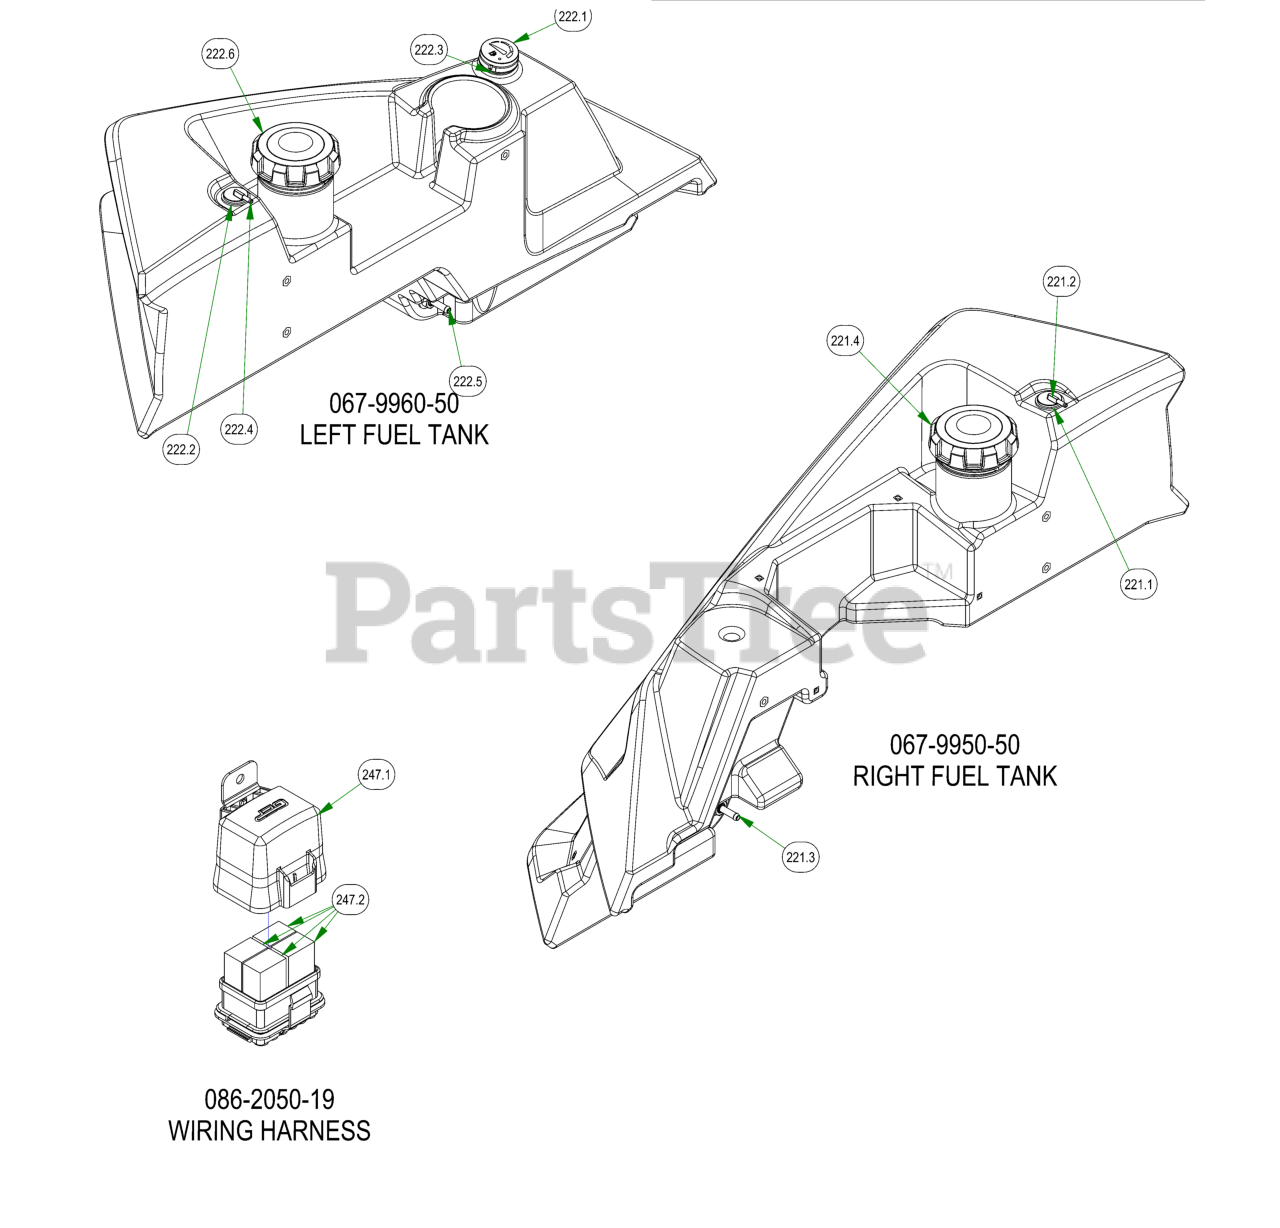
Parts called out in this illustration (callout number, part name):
221	2019 Right Rebel, Rogue, Renagade Fuel Tank (GAS)
221.1	Roll Over Valve Grommet
221.2	Rollover Valve
221.3	Fuel Pick-up
222	2019 Left Rebel, Rogue, Renegade Fuel Tank (GAS)
222.1	Fuel Gauge with Grommet
222.2	Roll Over Valve Grommet
222.3	Fuel Gauge Grommet
222.4	Rollover Valve
222.5	Fuel Pick-up
239.9	2022 Rebel Control Panel
240.9	2022 Rebel Control Panel
241.8	2022 Rebel Control Panel
247	2019 Wiring Harness-Rebel/Rogue
247.1	Relay Block Cover Replacement Kit
